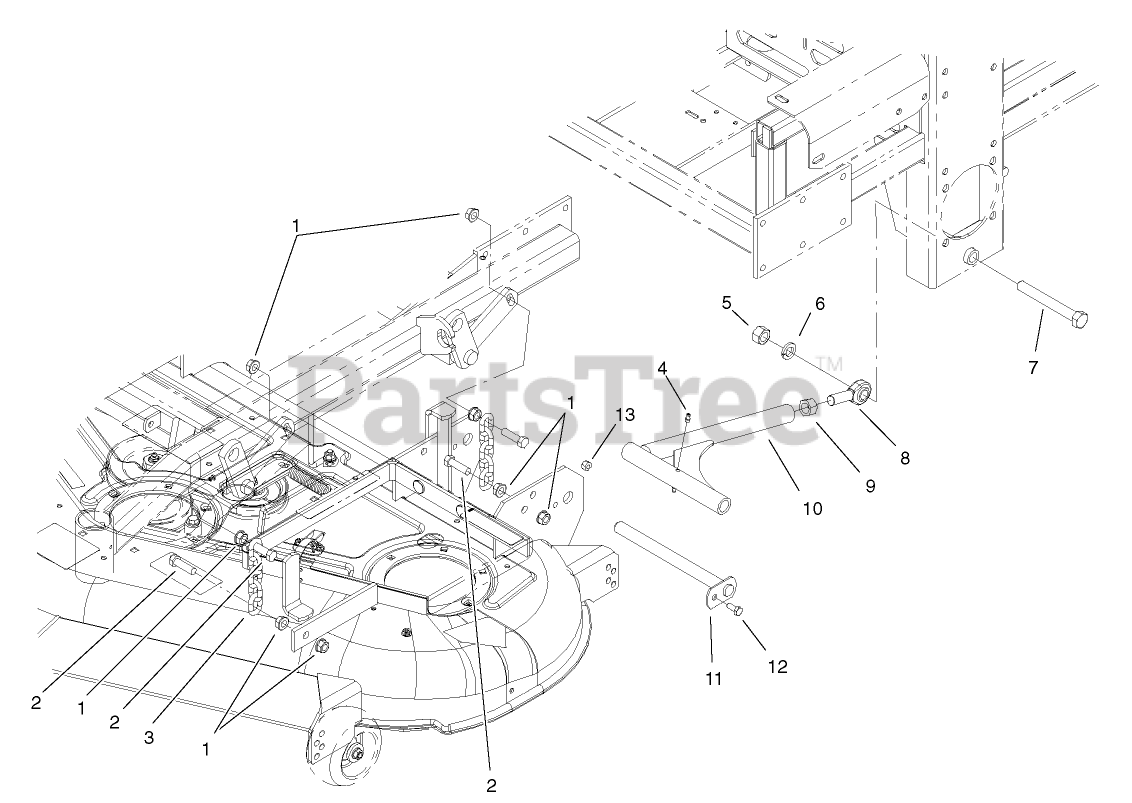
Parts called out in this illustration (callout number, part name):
1	NUT-HF
2	SCREW-CAP, HH
3	CHAIN-LIFT, DECK
4	FITTING-GREASE
5	NUT-HEX
6	WASHER-LOCK
7	SCREW-HH
8	BALLJOINT-SPHERICAL
9	NUT-HEX
10	STRUT
11	PIN-STRUT
12	SCREW-HH
13	NUT-LOCK, NI
